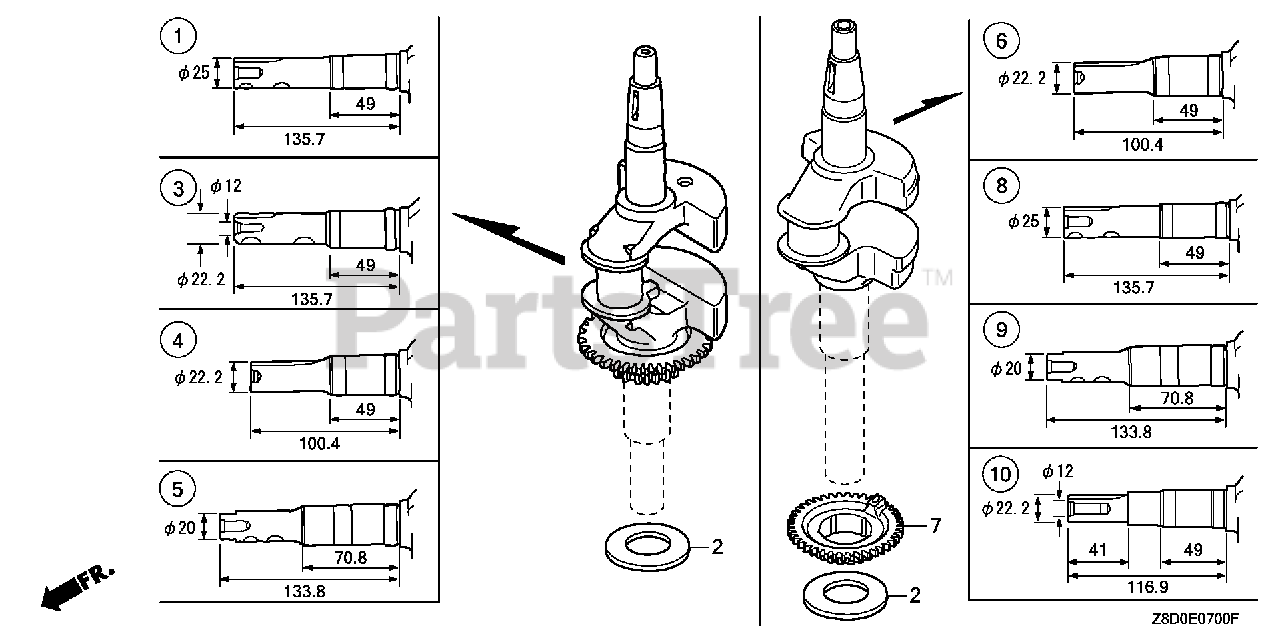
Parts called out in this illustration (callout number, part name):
1	CRANKSHAFT
2	WASHER, THRUST
7	PULLEY, TIMING BELT DRIVE
8	CRANKSHAFT
